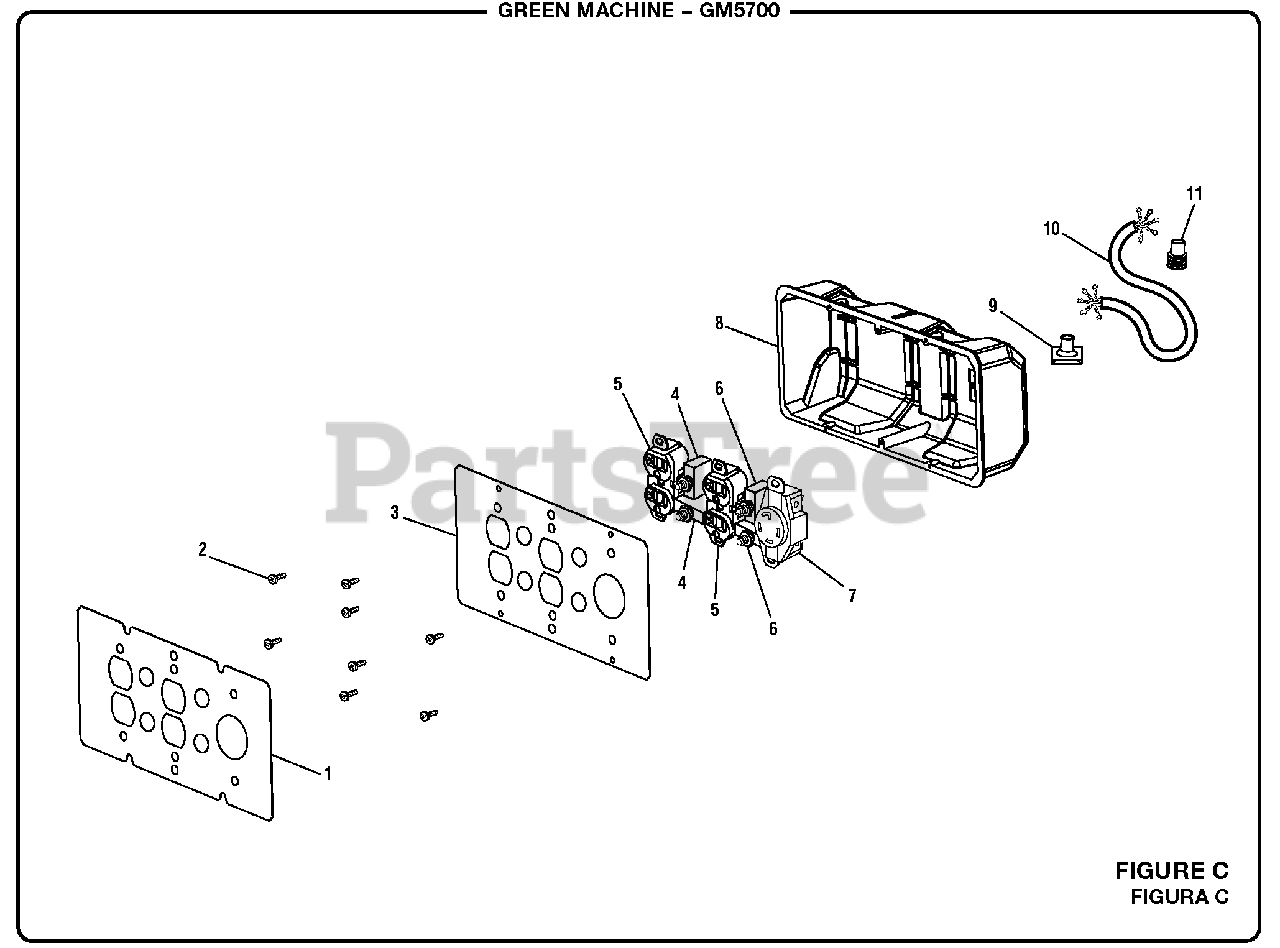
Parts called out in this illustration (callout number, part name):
1	Label (Power Outlet)
2	Screw (6-20 x 3/8 in.)
3	Front Panel
4	Circuit Breaker (20 Amp. 125 Volt)
5	120 Volt Duplex Receptacle
6	Circuit Breaker (30 Amp)
7	Twist Lock Receptacle (120/240 Volt, 30 Amp, L14-30R)
8	Control Box (Back Panel)
9	Rubber Boot (Control Panel Assembly)
10	Wiring Harness
11	Rubber Boot
